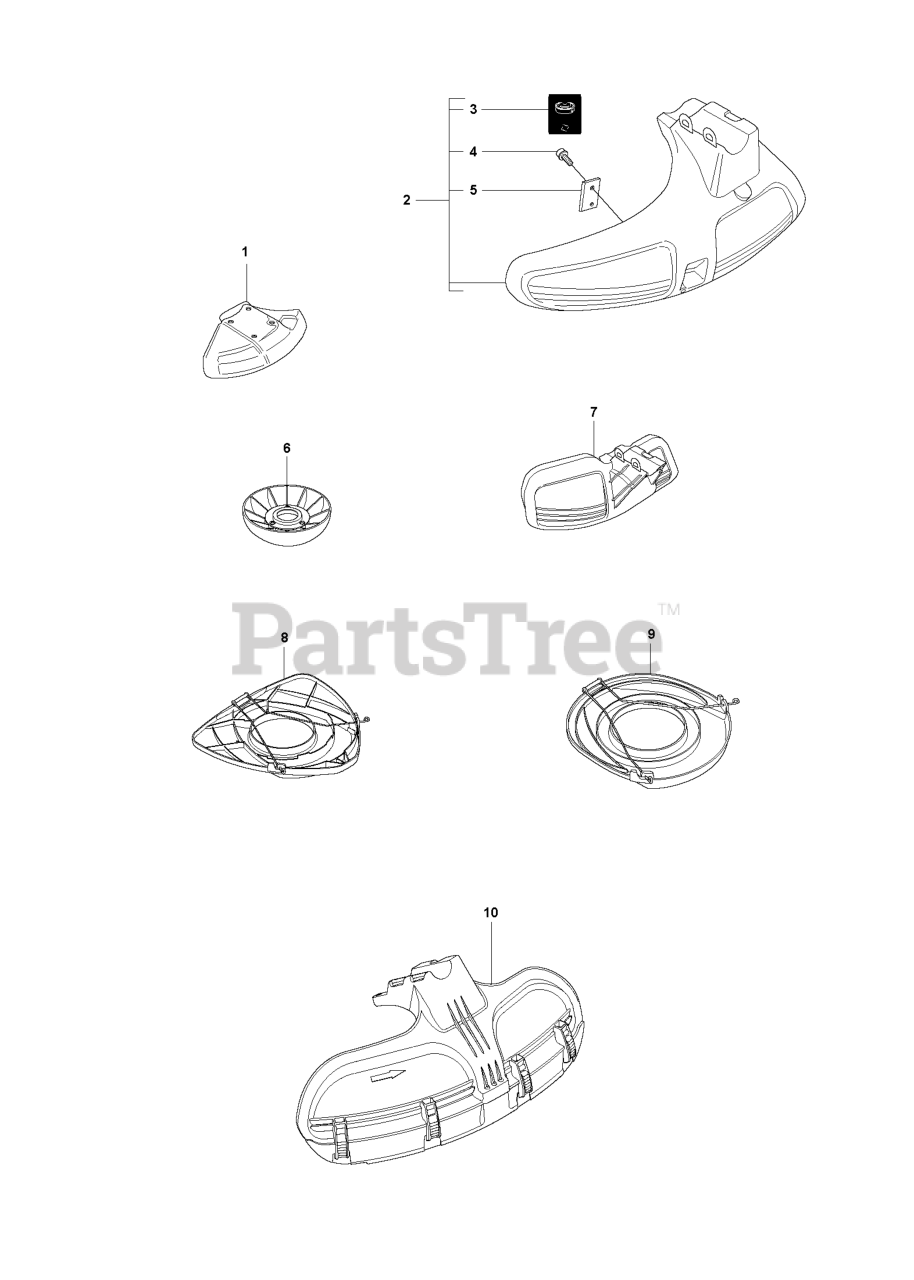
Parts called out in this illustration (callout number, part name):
1	BLADE GUARD SAW
1	METAL GUARD 200MM
2	TRIMMER GUARD W/ CUTTER
3	DECAL
4	SCREW
5	LINE CUTTER
6	SUPPORTING CUP
8	TRANSPORT GUARD
9	BLADE GUARD TRANSPORT
10	COMBINATION GUARD
